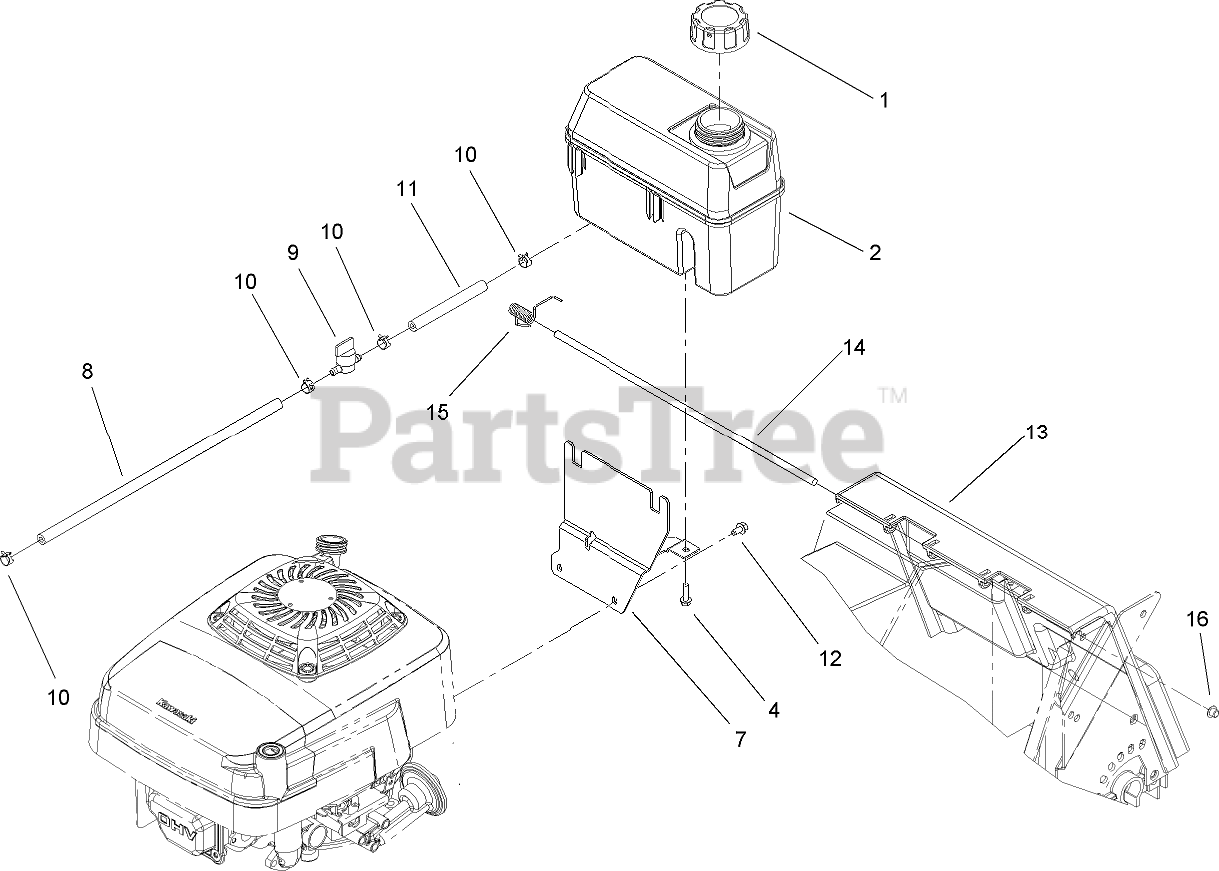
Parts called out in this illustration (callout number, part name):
1	CAP-GAS
2	Tank-Fuel
4	SCREW-HWH
7	TANK MOUNT ASM
8	HOSE-FUEL
9	VALVE-FUEL
10	CLAMP-HOSE
11	HOSE-FUEL
12	SCREW-HWH
13	DOOR-DISCHARGE, REAR
14	ROD-DOOR
15	SPRING-TORSION, DOOR
16	PUSHNUT-CAP, WASHER
